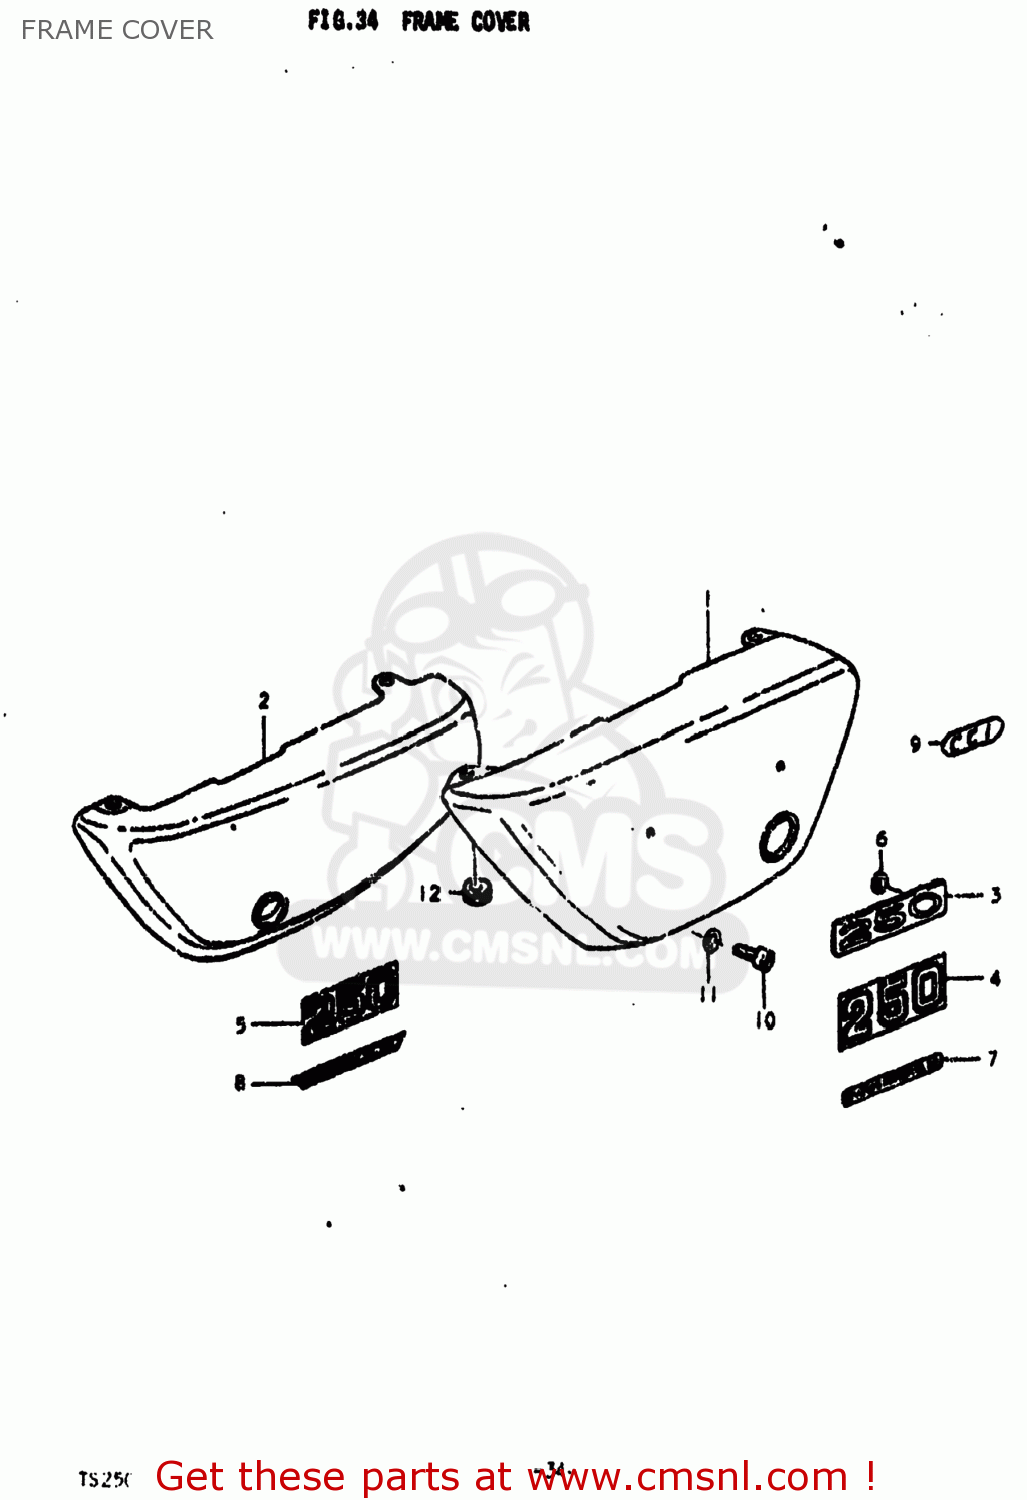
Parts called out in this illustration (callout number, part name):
1	COVER,FRAME,LEFT
2	COVER,FRAME,LEFT
3	EMBLEM,FRAME COVER
4	EMBLEM,FRAME COVER
5	EMBLEM,FRAME COVER
6	NUT
7	LABEL,COMPANY NAME
8	LABEL (COMPANY NAME)
9	EMBLEM,CCIS
10	SCREW(6X12)
11	WASHER
12	CUSHION
